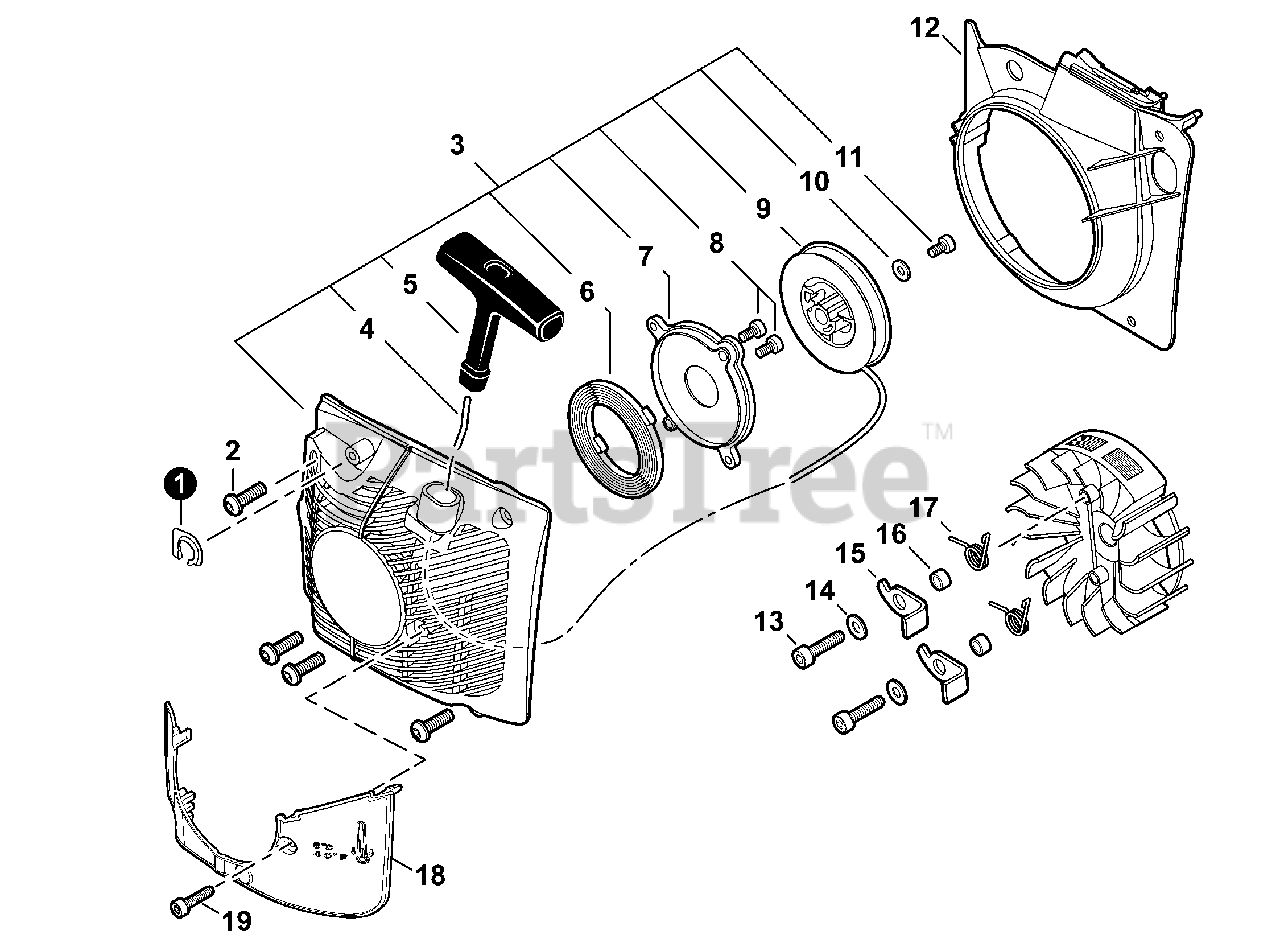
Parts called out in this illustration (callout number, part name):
1	PLATE, EYE
2	BOLT, TORX 5×20
3	STARTER ASSY, RECOIL
4	ROPE, STARTER 4×950
5	GRIP, STARTER
6	SPRING, RECOIL
7	PLATE, STARTER
8	BOLT, TORX 4×12
9	REEL, ROPE
10	WASHER 5.2×16×1.0
11	BOLT, TORX 5×10
12	COVER, FAN
13	BOLT, TORX 5×16
14	WASHER 5.5×12×0.8
15	PAWL, STARTER
16	SPACER 5.2×8×2.1
17	SPRING, TORSION
18	SHIELD KIT - SNOW
19	BOLT, TORX 4×12
